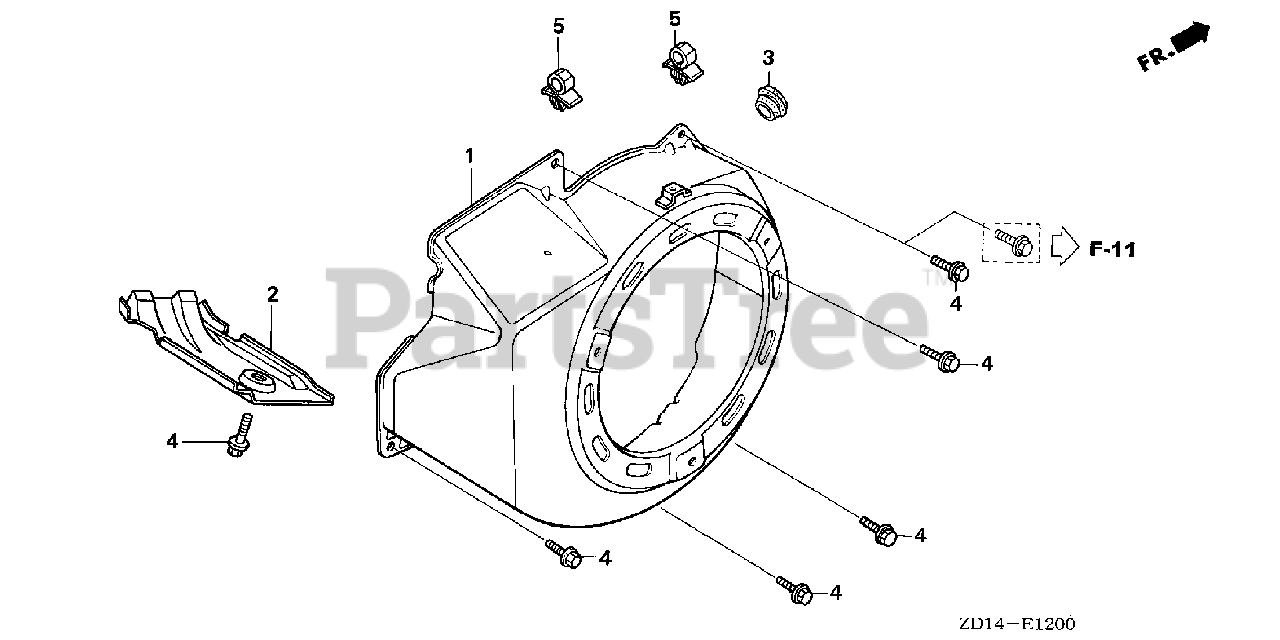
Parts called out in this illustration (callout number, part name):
1	COVER, FAN *NH1* (BLACK)
1	COVER, FAN *R280* (POWER RED)
3	GROMMET, DRAIN HOLE
4	BOLT, FLANGE (6X12) (CT200)
5	CLIP, WIRE HARNESS (6MM) (WHITE)
